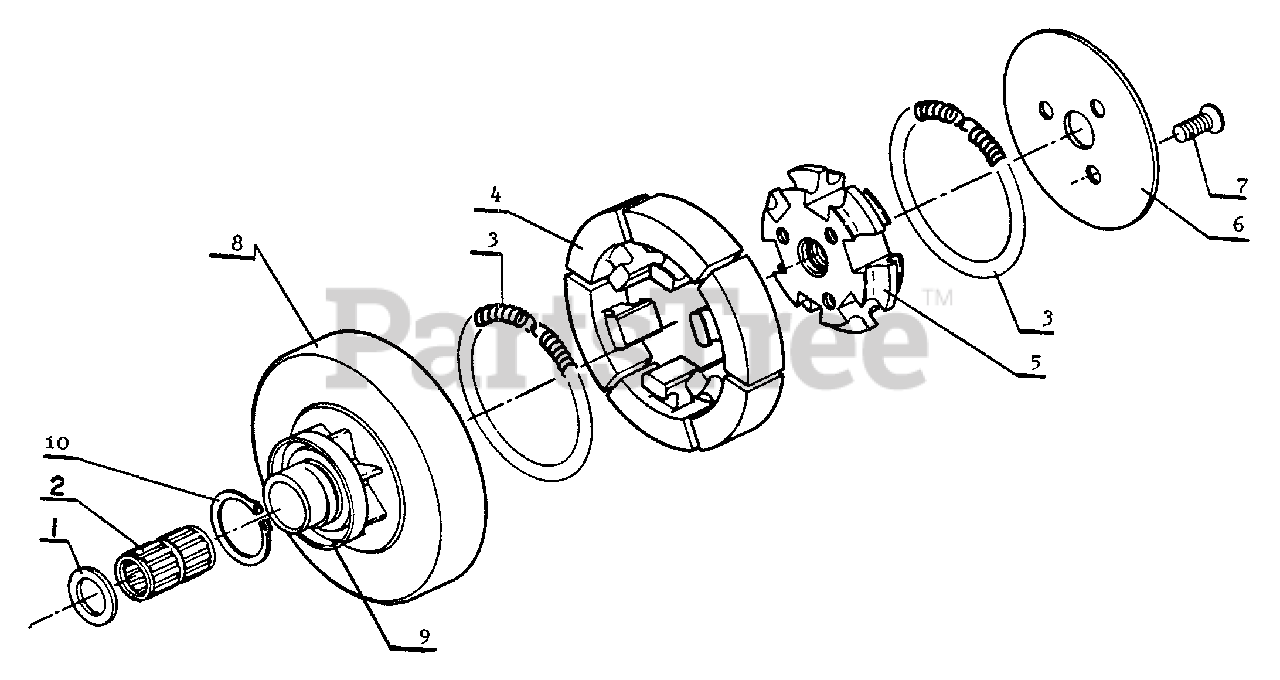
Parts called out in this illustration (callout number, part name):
1	WASHER, CLUTCH
2	BEARING, NEEDLE
3	SPRING, CLUTCH
4	SHOE, CLUTCH
5	HUB, CLUTCH
6	PLATE, CLUTCH
7	SCREW 5×16
8	CASE, CLUTCH
9	SPACER
10	RING, RETAINING - 20
